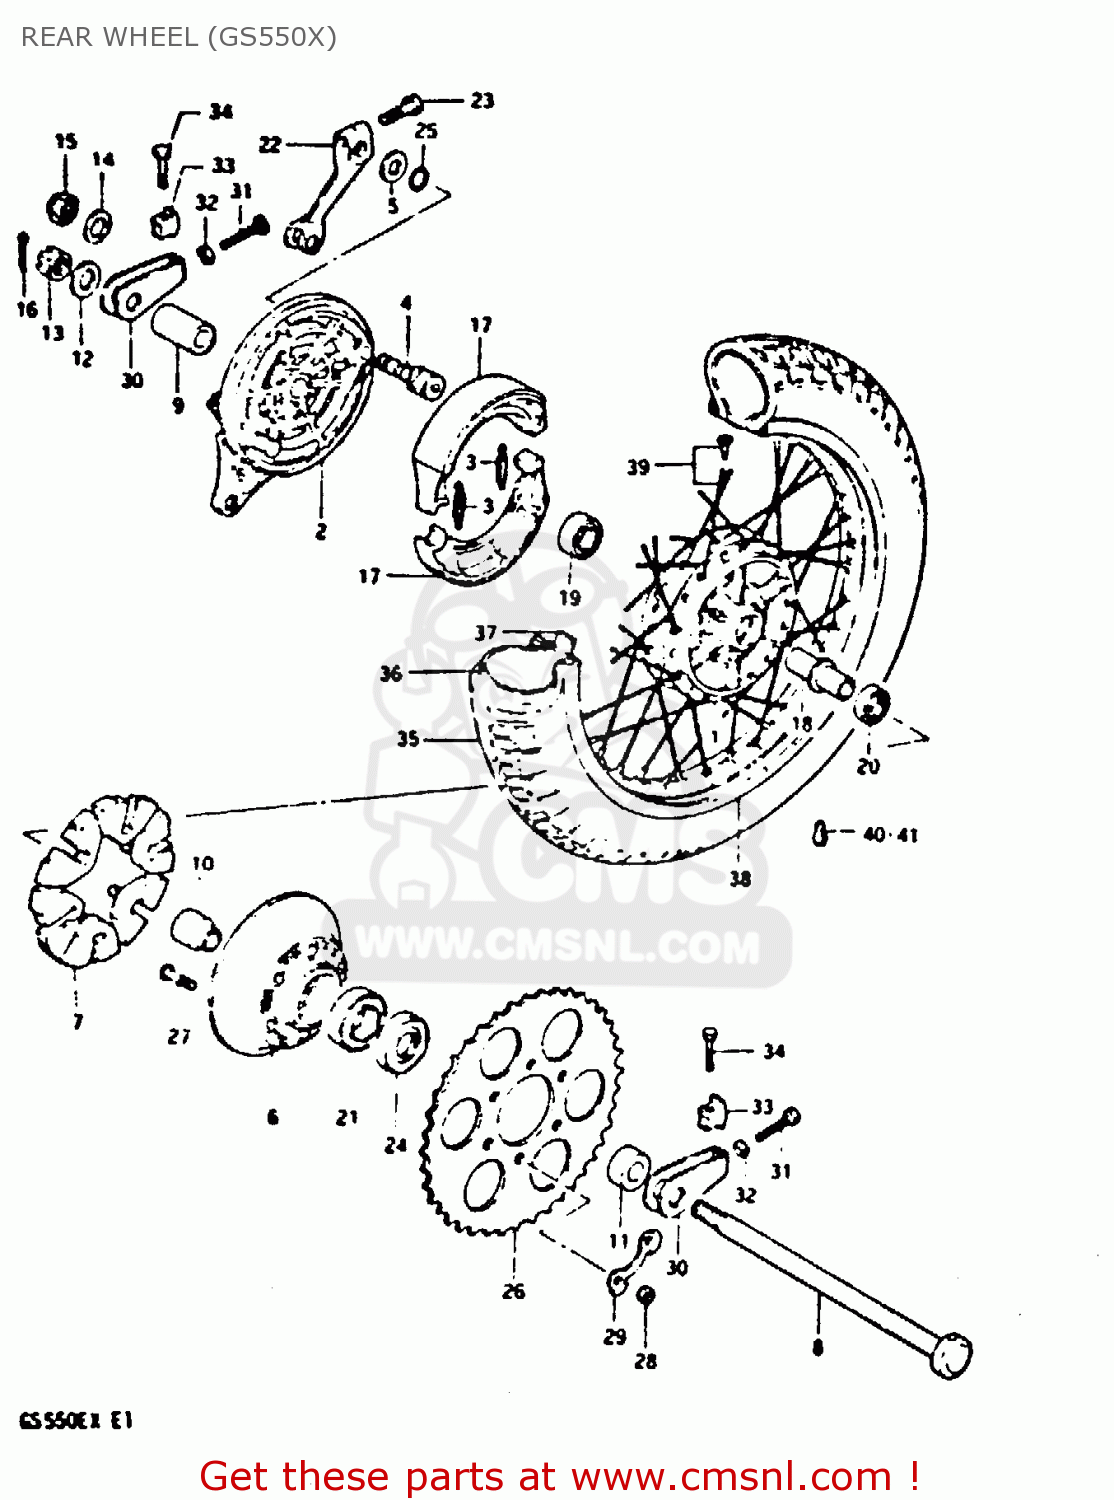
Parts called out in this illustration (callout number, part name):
1	DRUM,REAR HUB
2	PANEL,REAR HUB
3	SPRING,BRAKE SHOE
4	CAM,FRONT BRAKE
5	WASHER (15X24X1.6)
6	DRUM,REAR SPROCKET MOUNT
7	CUSHION,REAR DRUM
8	AXLE,REAR
9	SPACER, RH
10	SPACER,REAR HUB BEARING
11	SPACER(17X30.5X22.3)
12	WASHER (17X30X3.2)
13	NUT
16	PIN,COTTER
17	SHOE,BRAKE
18	SPACER
19	BEARING
20	BEARING
21	BEARING
22	LEVER,RR BRAKE CAM
23	BOLT
24	SEAL,OIL(30.5X52X8)
25	O-RING,BOSS
26	SPROCKET,REAR
27	BOLT
28	NUT
29	WASHER
30	ADJUSTER,CHAIN
31	BOLT
32	NUT
33	SUPPORTER,CHAIN ADJUST
34	BOLT
35	TIRE
36	TUBE ASSEMBLY,WHEEL,INNER
37	PROTECTOR,WHEEL,INNER
38	RIM,WHEEL
39	SPOKE SET,REAR
40	BALANCER,WHEEL (B)
41	BALANCER,WHEEL (30G)
